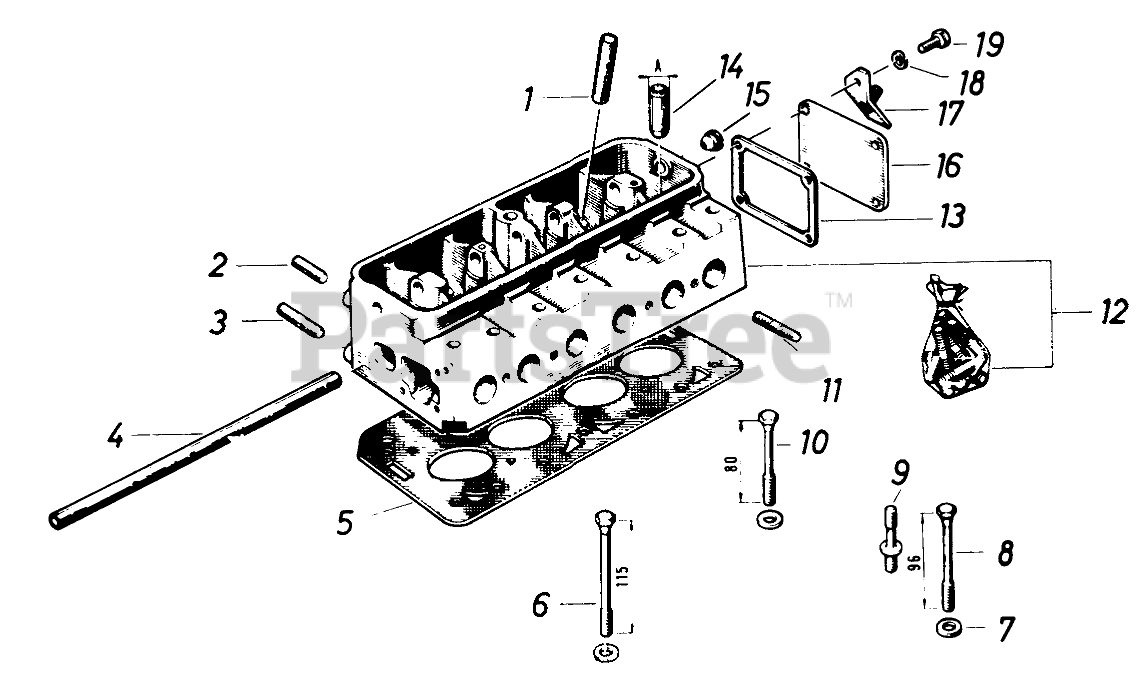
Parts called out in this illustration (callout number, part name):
4	Cooling Tube
5	Cylinder-Head Gasket
6	Screw
7	Washer
8	Screw
10	Screw
12	Cylinder-Head
13	Gasket
14	Valve Guide A11.10
16	Cover-Cylinder Head
17	Bracket for Carb
18	Lock Washer
19	Screw
